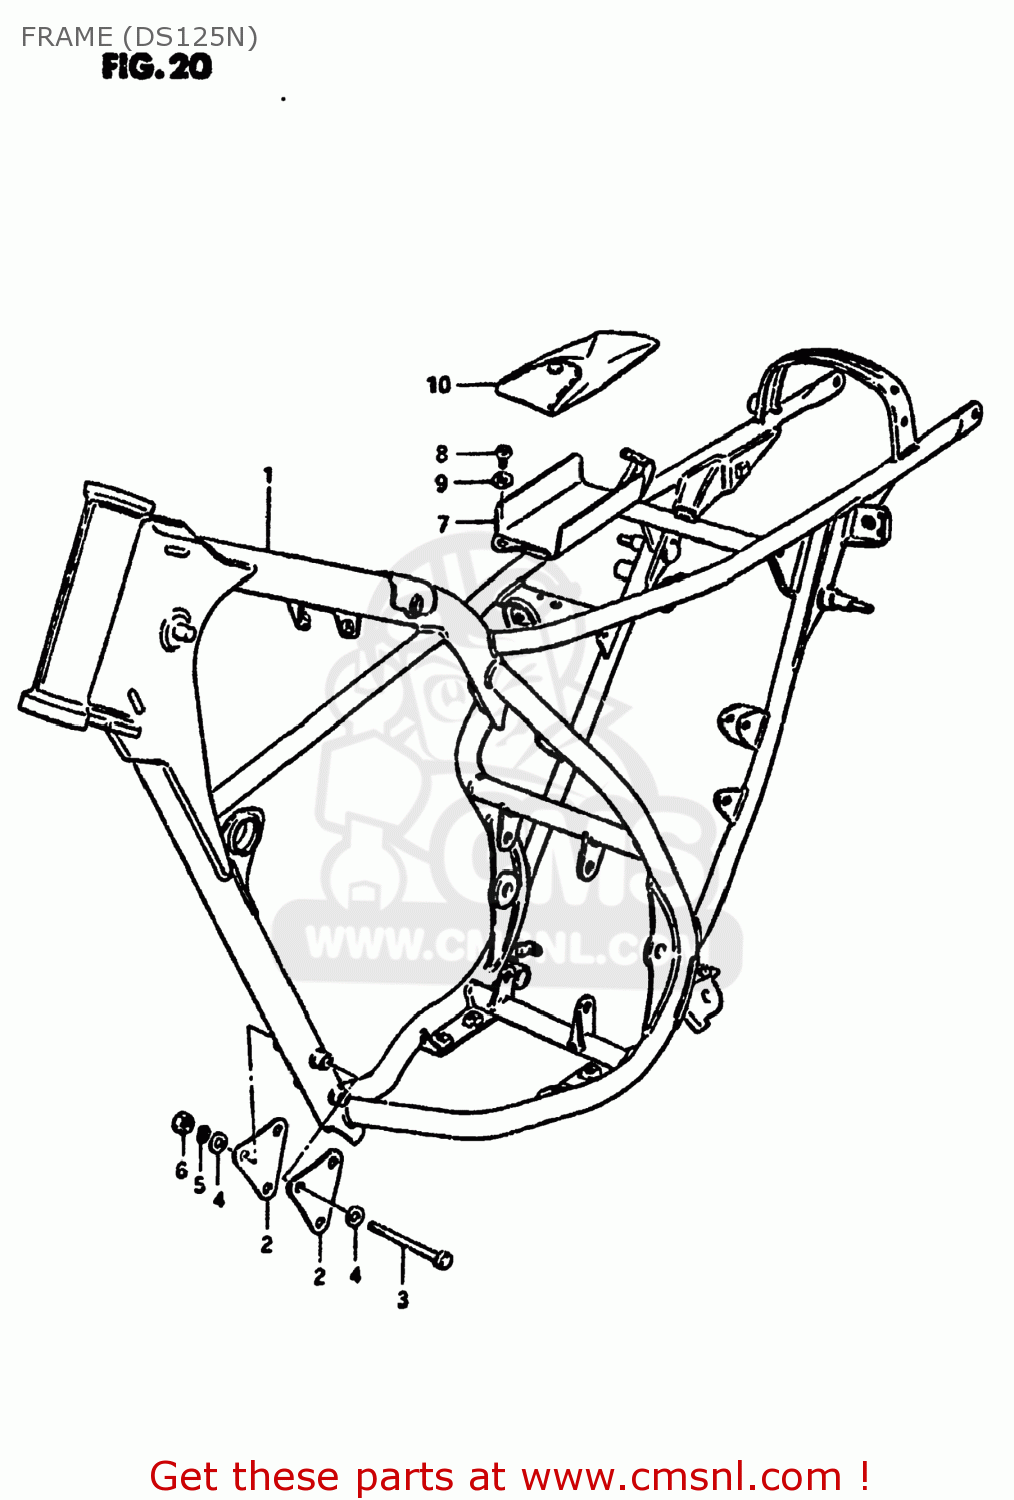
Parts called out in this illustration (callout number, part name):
1	FRAME
2	PLATE,ENG MTG
3	BOLT,8X75
4	WASHER
5	LOCK WASHER
6	NUT
7	HOLDER,TOOL
8	SCREW
9	WASHER
10	TOOL SET
